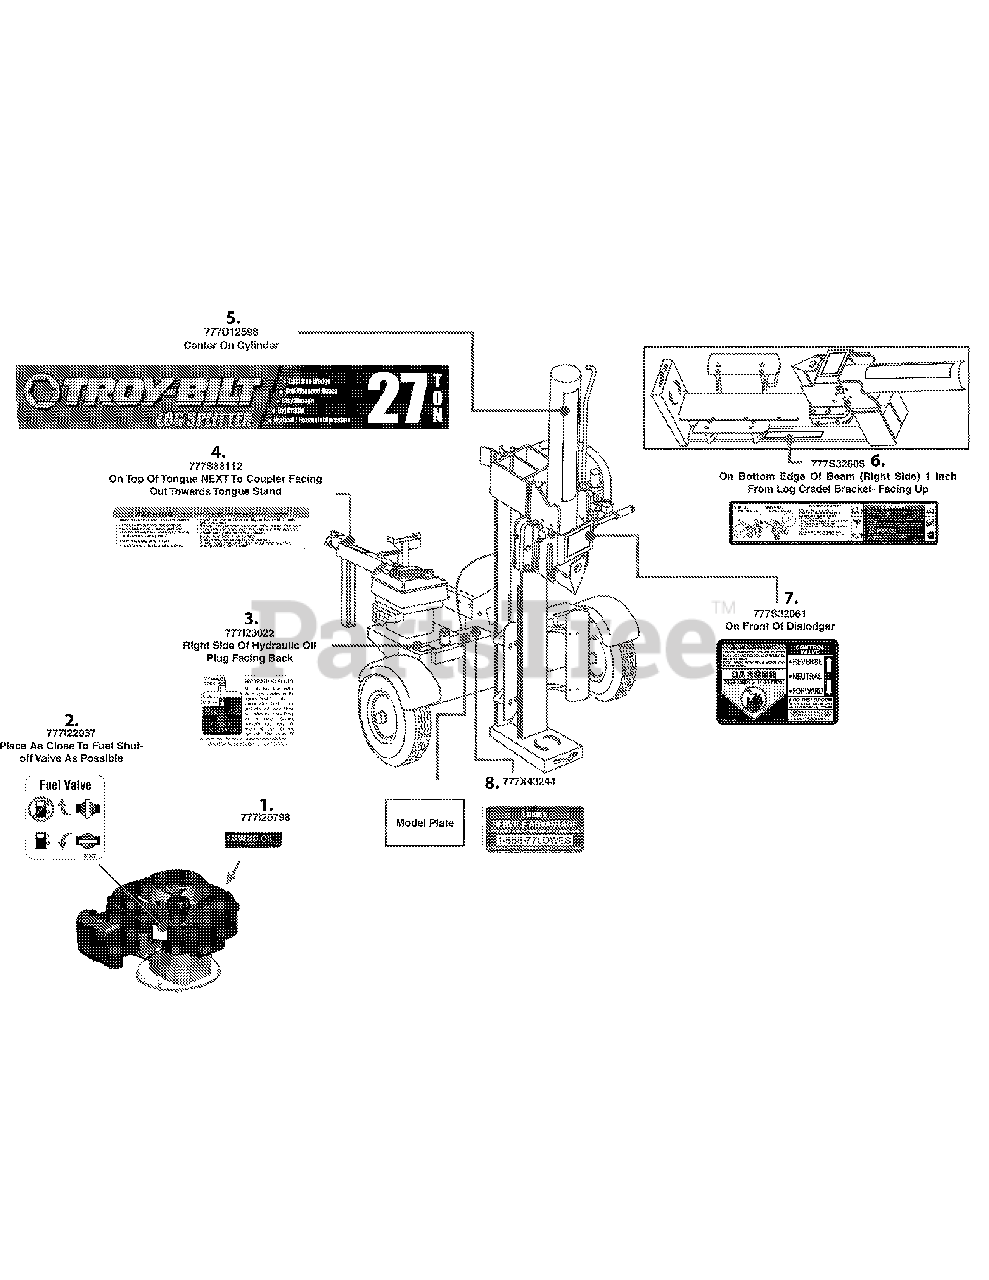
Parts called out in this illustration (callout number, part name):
1	LABEL-SHROUD
2	LABEL-SHROUD
3	LABEL-LGSPLT:HYRAULICFLUID
4	LABEL-LGSPLT:MOVNG/TOW:WRNG
5	LABEL-LGSPLT:CYL:27T:TBILT
6	LABEL-BEAM DNGR INSTR
7	LABEL-CNTRL VALVE
8	LABEL, Lowes
